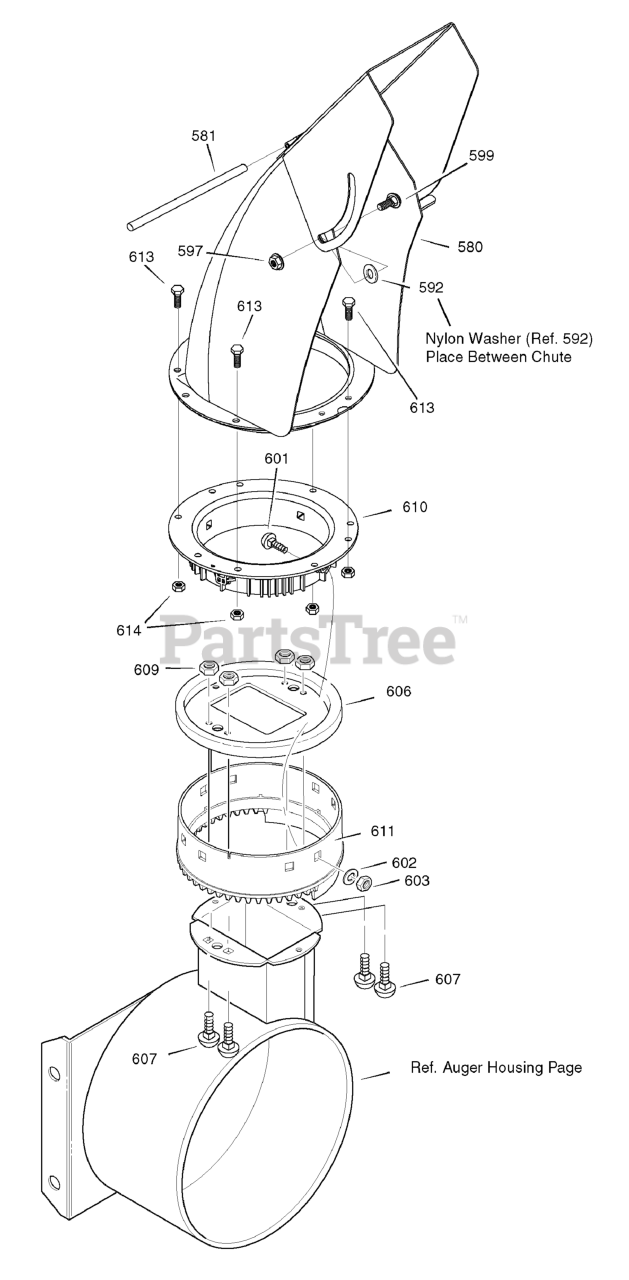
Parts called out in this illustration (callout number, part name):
580	CHUTE ASSEMBLY
581	PIN, HINGE
592	WASHER, Nylon
597	NUT, Hex-Flange, 5/16-18
599	BOLT, 5/16-18 X .75
601	BOLT, 5/16-18 X 1.00
602	WASHER, Flat
603	NUT, Hex, Nylock, 5/16-18
606	CHUTE COLLAR
607	SCREW, 1/4-20 X 0.75
609	NUT, 1/4-20 Hex Nylock
610	RING, Retainer, Inner
611	RING, Retainer, Outer
613	CAPSCREW, Hex-Flange, 1/4-20 x .75
614	NUT, Nylock Flanged, 1/4-20
